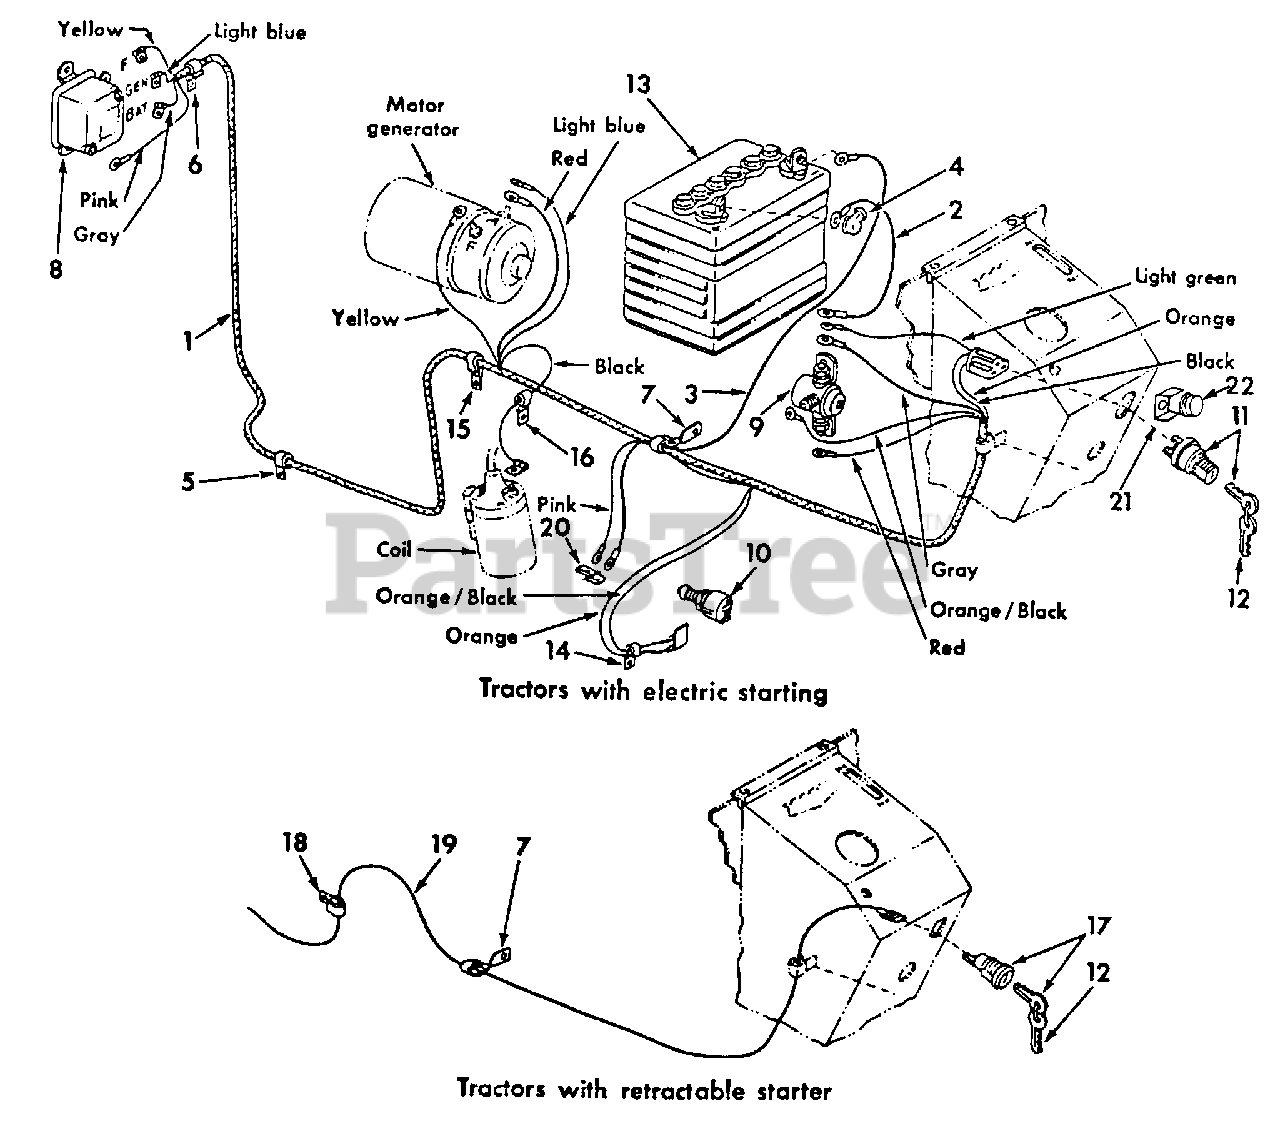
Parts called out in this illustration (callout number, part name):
1	Harness Assy, Cable
2	Cable Assy, Battery to Magnetic Switch
3	Cable Assy, Battery to Ground
4	Cover, Battery Terminal
5	Clip, Cable Harness
6	Clip, Cable Harness
7	Clip, Cable Harness
8	Regulator, Voltage
9	Switch Assy, Magnetic
10	Switch Assy, Safety Starting
11	Switch Assy, Ignition
12	Key, Switch
13	Battery, Prestolite 9948X (12 Volt)
14	Clip, Cable
15	Clip, Cable Harness
16	Clip, Cable
17	Switch Assy, Magneto Ignition
18	Clip, Cable
19	Cable Assy, Magneto Ignition
20	Clip, Safety Starting Switch Cable Snap On
21	Retainer, Ignition Switch
22	Socket, Ignition Switch
